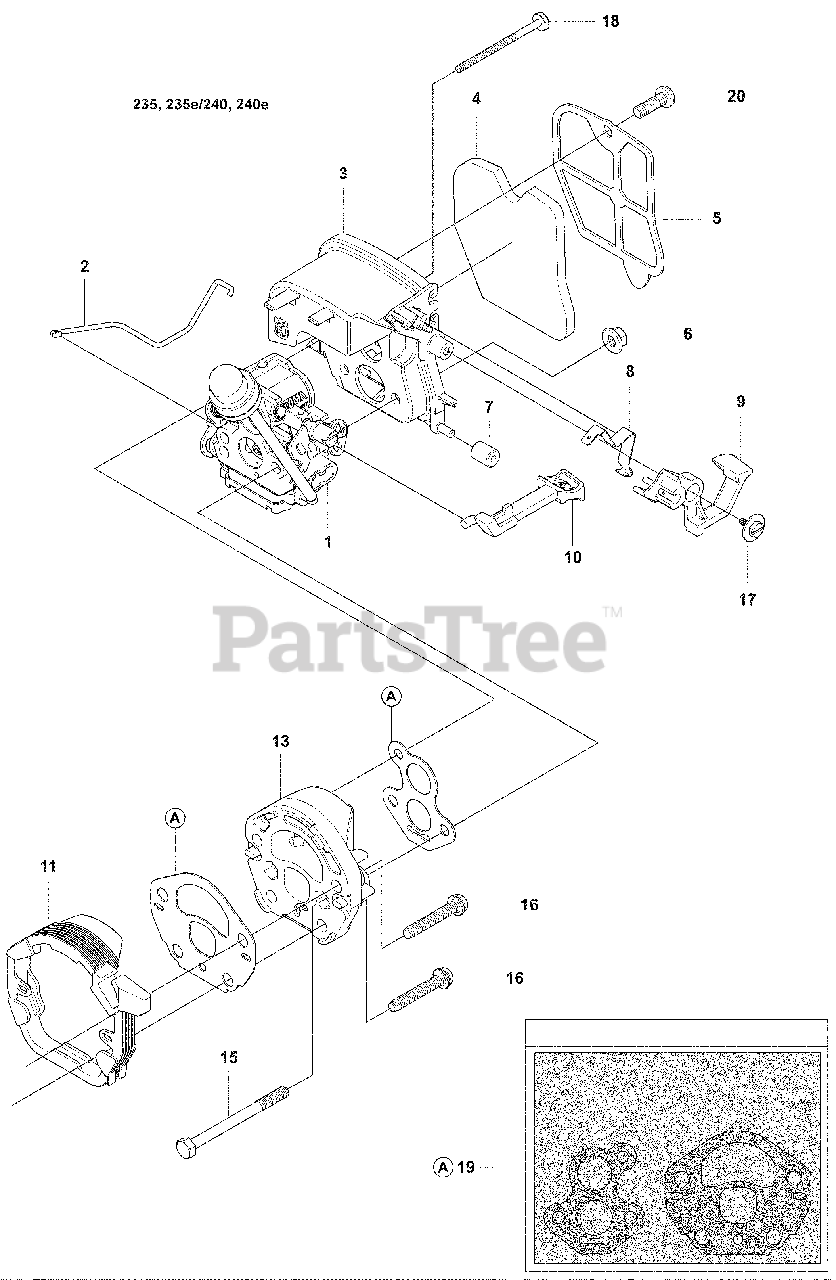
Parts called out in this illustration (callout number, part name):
1	CARBURETOR (ZAMA) - Ref.
2	THROTTLE WIRE
3	FILTER HOUSING
4	AIR FILTER
5	FILTER PLATE
7	ISOLATOR FILTER HOUSING
8	SWITCH, SPRING
9	SWITCH LEVER
10	CHOKE KNOB
11	CARB ADAPTOR SEAL
13	CARB ADAPTOR
15	STUD-CARBURETOR
16	CARB ADAPTOR SCREW
17	SCREW SWITCH
18	TOP STUD-CARBURETOR
19	GASKET KIT
20	SCREW, FILTER PLATE
